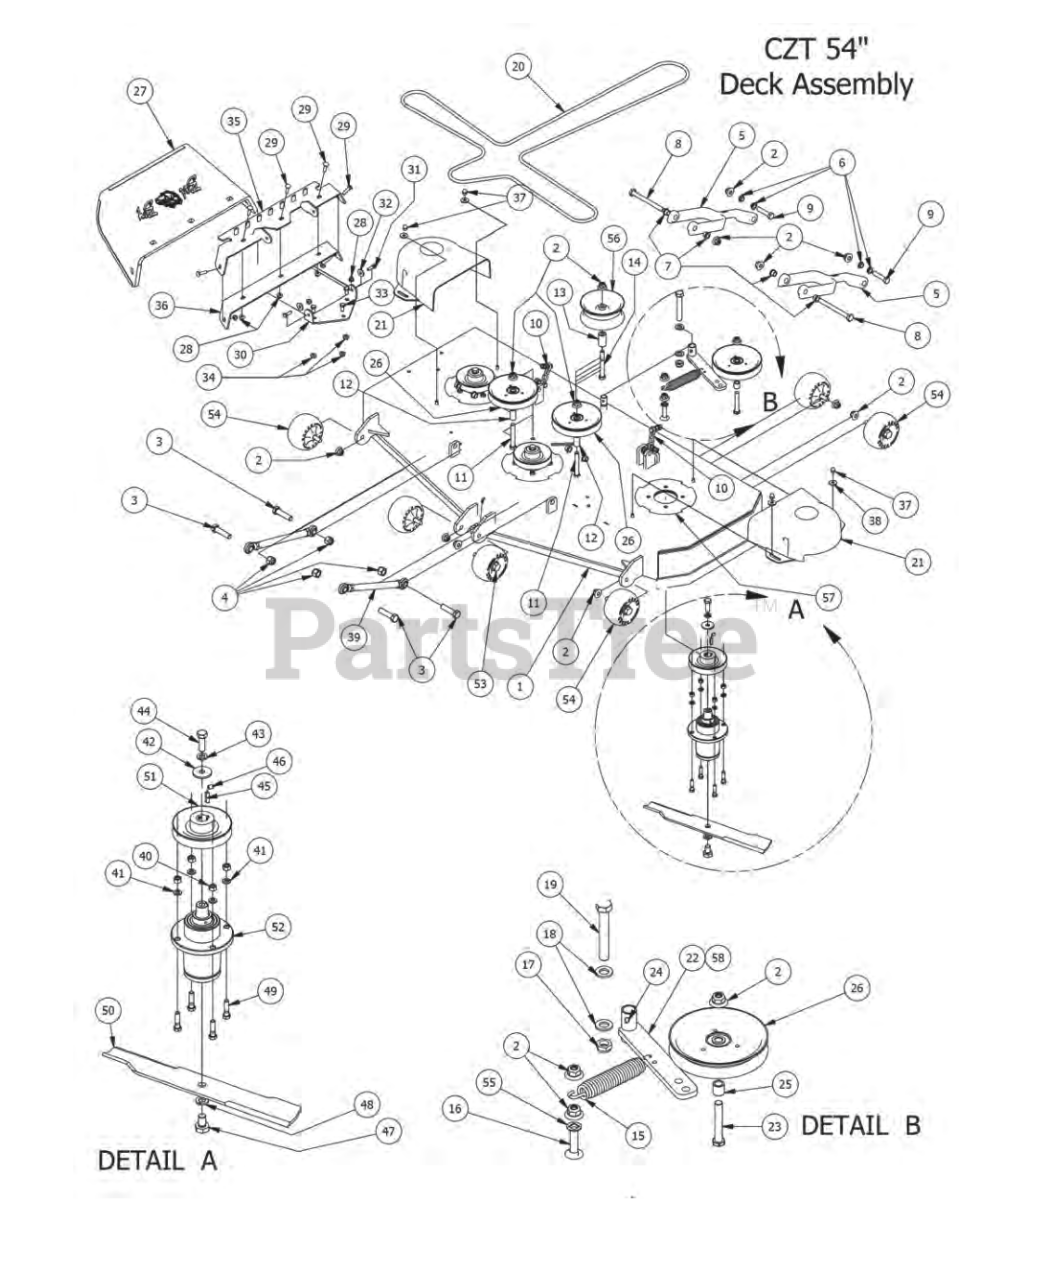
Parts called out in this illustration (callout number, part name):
1	2014 ZT/CZT 54" Deck
2	1/2-13 Nylon Flange Nut-Orange
3	5/8" x 2 1/2" Gr5 Hex Bolt (Coarse)
4	5/8 Std NC Nylock Nut
5	Deck Arm Assembly
6	Flange for Lower Deck Arm
7	Flange Bushing For Deck Arm upper
8	1/2" x 5 1/2" Bolt
9	1/2-13X 2-1/4 GR Hex Bolts
10	2015 CZT Deck Hanger Chain
11	1/2 x 3 1/2 Flange Bolt Grade 8
12	.502 ID X.75 OD X 1.500 Leng
13	1 3/4" Pulley Spacer
14	1/2" x 4" Bolt (Grade 8)
15	2009 Deck/Pump Idler Spring
16	1/2 x 2" Carriage Bolt
17	5/8-11 Nylon Insert Jam Half Nut
18	.635 ID Plastic Washer
19	5/8" x 4" Hex Bolt
20	B155.75 Belt
21	2014 ZT Pulley Cover
22	Deck Idler
23	1/2-13 x GR 5 Hex Bolt Zinc
24	1/4" Press in Grease Fitting
25	3/4 OD x 1/2 ID x 314 Length
26	5-3/4 Idler Pulley
27	Rubber Discharge Chute
28	5/16" Nylon Flange Nut
29	5/16" x 1 1/4" Carriage Bolt
30	Discharge Chute Hanger (deck mounted)
31	5/16" x 1" Bolt
32	.360 ID Plastic Washer
33	3/8" x 3/4" Hex Bolt
34	3/8" Flange Nut
35	60" Discharge Chute Upper Hanger
36	60" Lower Hanger
37	Acorn nut-pulley Cover
38	.360 ID Plastic Washer-Black
39	Turnbuckle (Top Link)
40	3/8" Hex Nut
41	3/8" Lock Washer
42	1/2 Belleville Washer
43	1/2" Lock Washer
44	1/2"-20 x 1 1/2 - Grade 5 Fine Thread Bolt
45	1/4" x 1" Key
46	5/16 Set Screw
47	5/8" x 1 1/2" Gr8 Hex Bolt (Fine)
48	5/8" Lock Washer
49	3/8" x 1 1/2" Hex Bolt
50	54" Deck Fusion Blade For Outlaw
51	5" Deck Pulley
52	ZT/CZT SPINDLE ASSEMBLY
53	Deck Wheel Bolt
54	Anti-Scalp Rollers
55	517 Square Hole Round Washer
56	5 3/4" Deck Idler Pulley
57	Deck Spindle Support Plate 72 inch
58	Deck Idler Assembly (Components 49,50,51,52,53)
